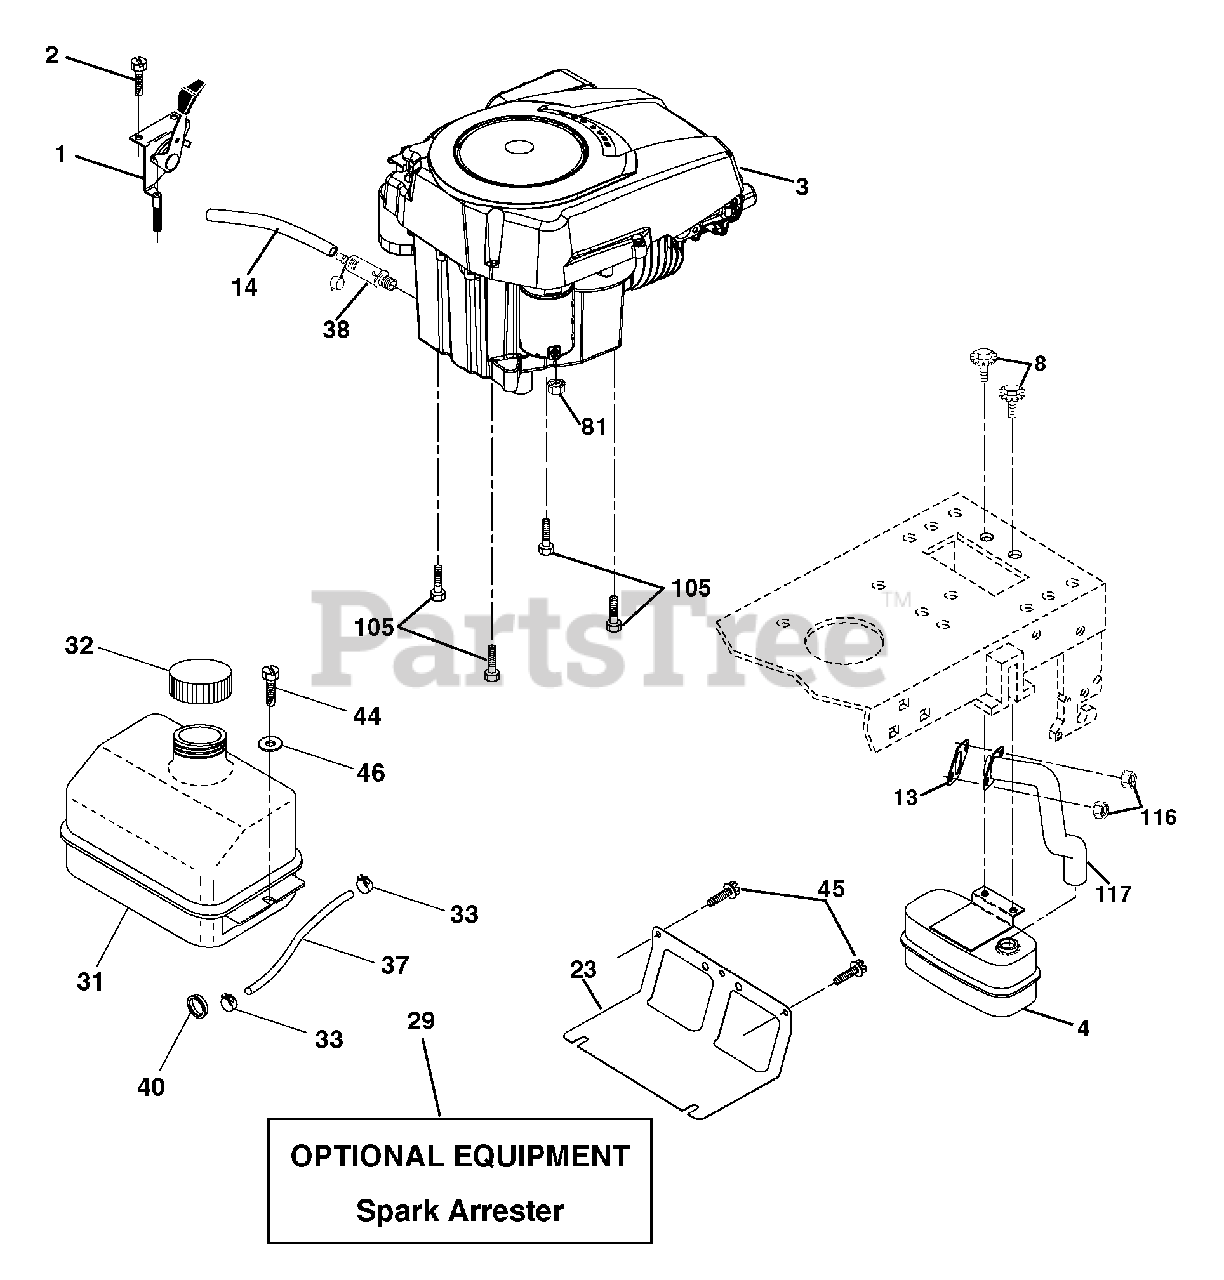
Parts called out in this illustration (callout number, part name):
1	Control, Throttle/Choke
2	Screw Hex Thd Cut 1/4-20 x 1/2
8	Bolt 5/16-18 unc x 3/4 w/Sems
13	Muffler Gasket
14	Tube Oil Drain
23	Shield, Browning/Debris Guard
29	Arrester, Spark
31	Tank, Fuel
32	Cap, Fuel
33	Clamp, Hose Blk
37	Line, Fuel
38	Plug Drain Oil Easy
40	Bushing Snap
44	Screw 1/4-20 x 3/4
45	Screw Hex Wsh Thdrol 3/8-16 x 3/4
46	Washer 9/32 x 7/8 x 16 Ga.
81	Nut Keps Hex 1/4-20 unc
105	Screw 3/8-16 x 1
116	Nut Hex Flange Toplock M8-1.25
117	Exhaust Tube LH
